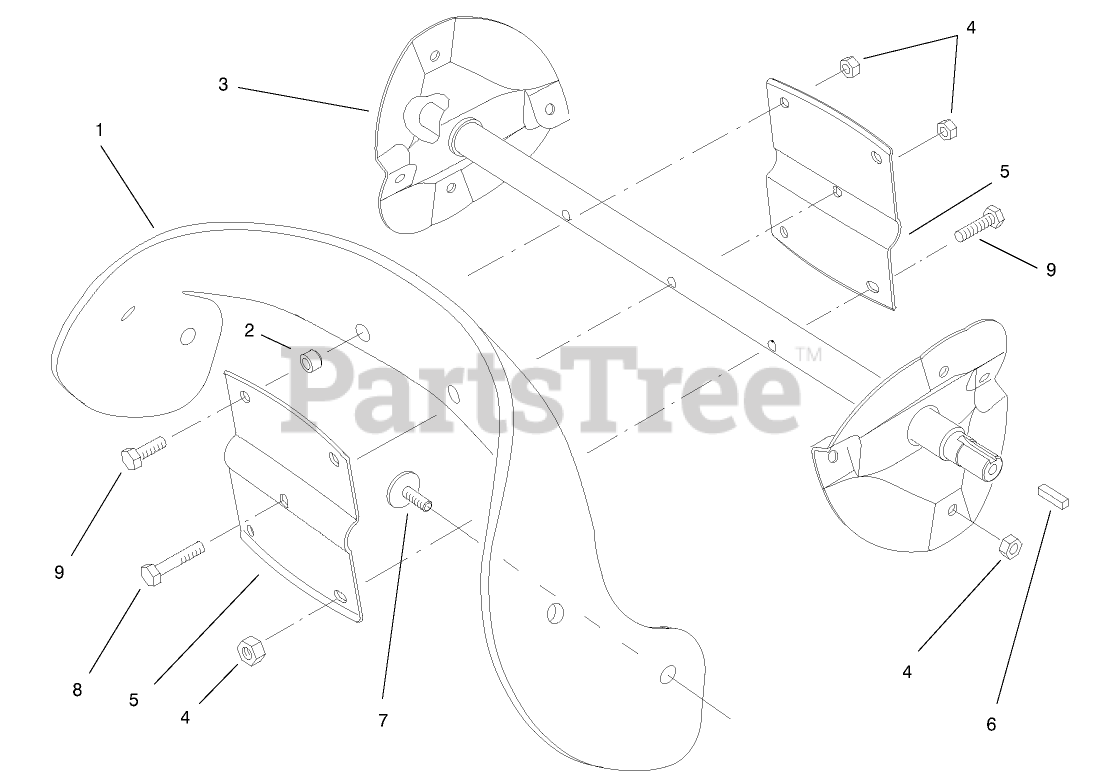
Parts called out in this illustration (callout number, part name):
1	BLADE-ROTOR
2	SPACER-BLADE, ROTOR
4	NUT-LOCK, NI
5	HALF-ROTOR
6	KEY-SQUARE
7	SCREW
8	SCREW-HH
9	SCREW-HH
